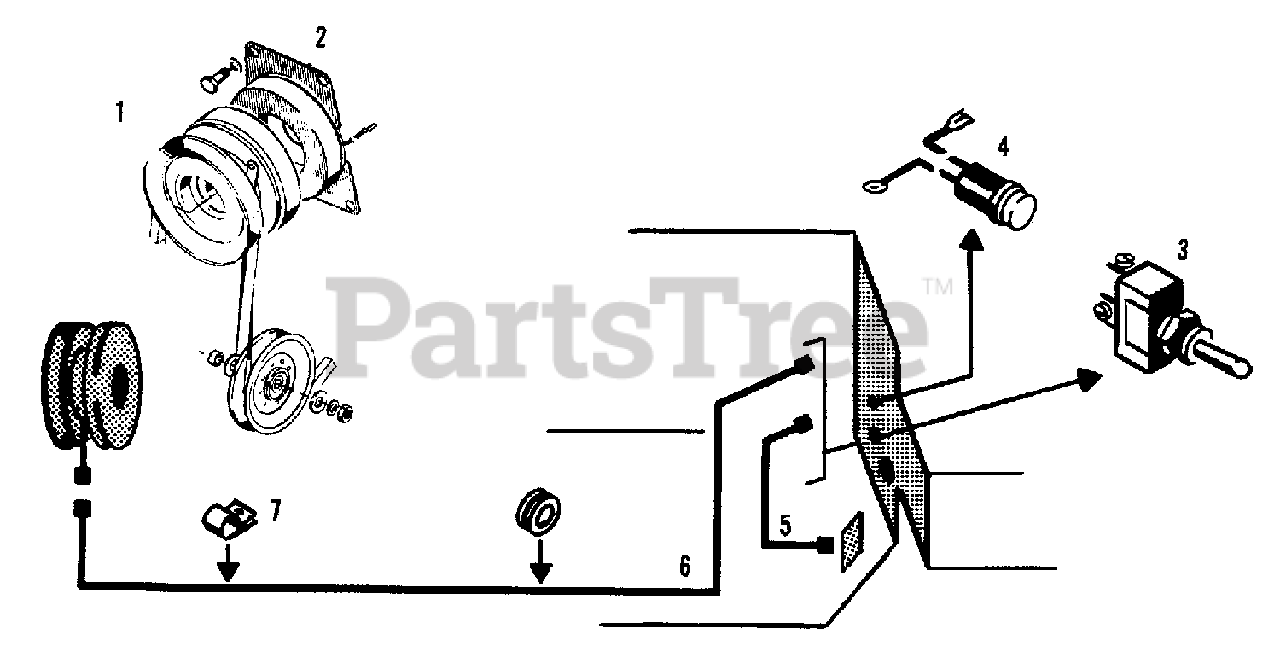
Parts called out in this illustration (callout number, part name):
1	HUB, Electric Clutch
1	KEY, 1/4 x 1/4 x 5/8 Parallel
2	COIL, Clutch
3	SWITCH, Toggle
3	PLUG 7/8 " Button
4	LAMP, Pilot
5	LEAD, Wire (Buss Post To Switch)
6	LEAD, Wire (Switch To P.T.O. Clutch)
7	CLIP, Cable #3 Closed
